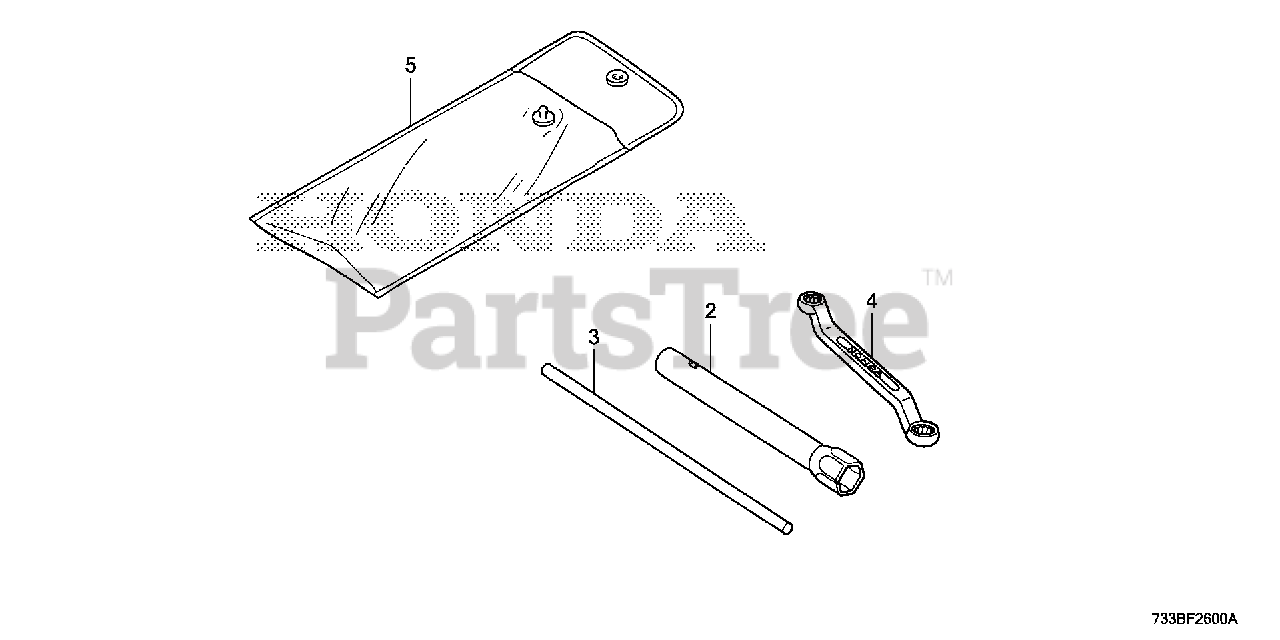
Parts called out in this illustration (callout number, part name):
2	WRENCH, SPARK PLUG
3	HANDLE, BOX WRENCH (NOT AVAILABLE)
4	WRENCH, EYE (10X12)
5	BAG, TOOL (230MM)
